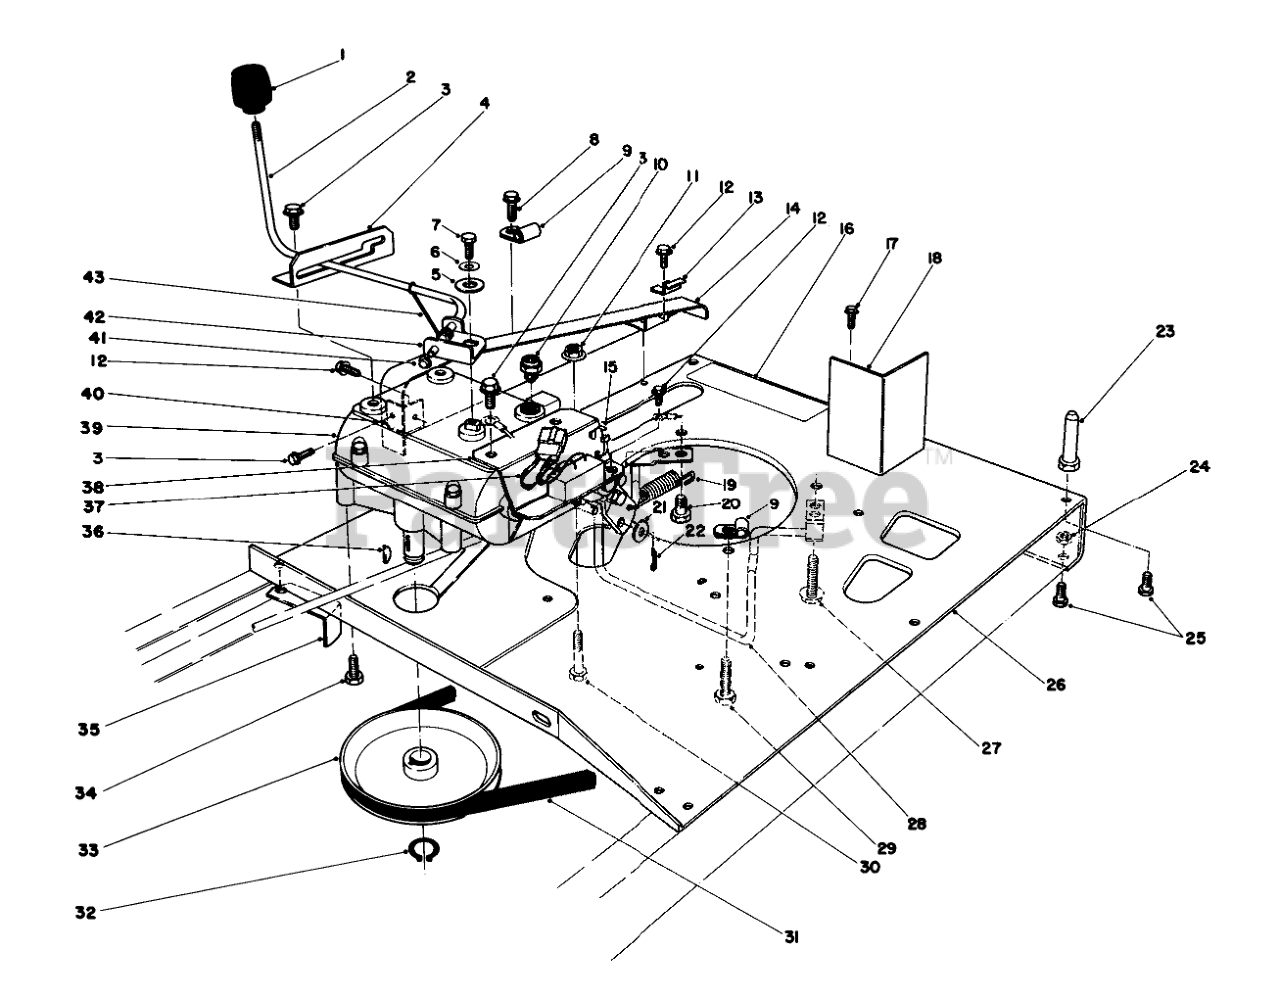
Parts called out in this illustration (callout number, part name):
2	SHIFT LEVER
3	SCREW-HWHTF
4	SHIFT LEVER GATE
5	WASHER-FLAT
6	WASHER-BELLEVILLE
7	SCREW-HH
8	SCREW-HHFTF
9	CLIP-FUEL LINE
10	NEUTRAL SWITCH
11	NUT-HF
12	SCREW
13	Clamp-Cable
14	Chain Guard
15	TIE-CABLE
16	DECAL
17	SCREW-HH
18	Baffle-Carb
19	SPRING-RETURN, BRAKE
20	Screw-HH
21	WASHER-FLAT
22	PIN-COTTER
23	PIN-MOUNTING, LOWER
24	NUT-LOCK, NI
25	SCREW-HH
26	Plate-Engine
27	SCREW-HWHTF
28	Belt Guide
29	SCREW-HH
30	SCREW-HH
31	V-BELT
32	RING-SNAP, EXTERNAL
33	PULLEY
34	5/16-18 X 5/8 SEMS SC
35	TRANS BELT RET B
36	KEY-WOODRUFF
37	INTERLOCK MODULE
38	Mount Module
39	TRANSMISSION
40	CHAIN GUARD BRKT B
41	RETAINER-PUSH ON
42	SHIFT LEVER CLAMP
43	Spring-Shift Rod
